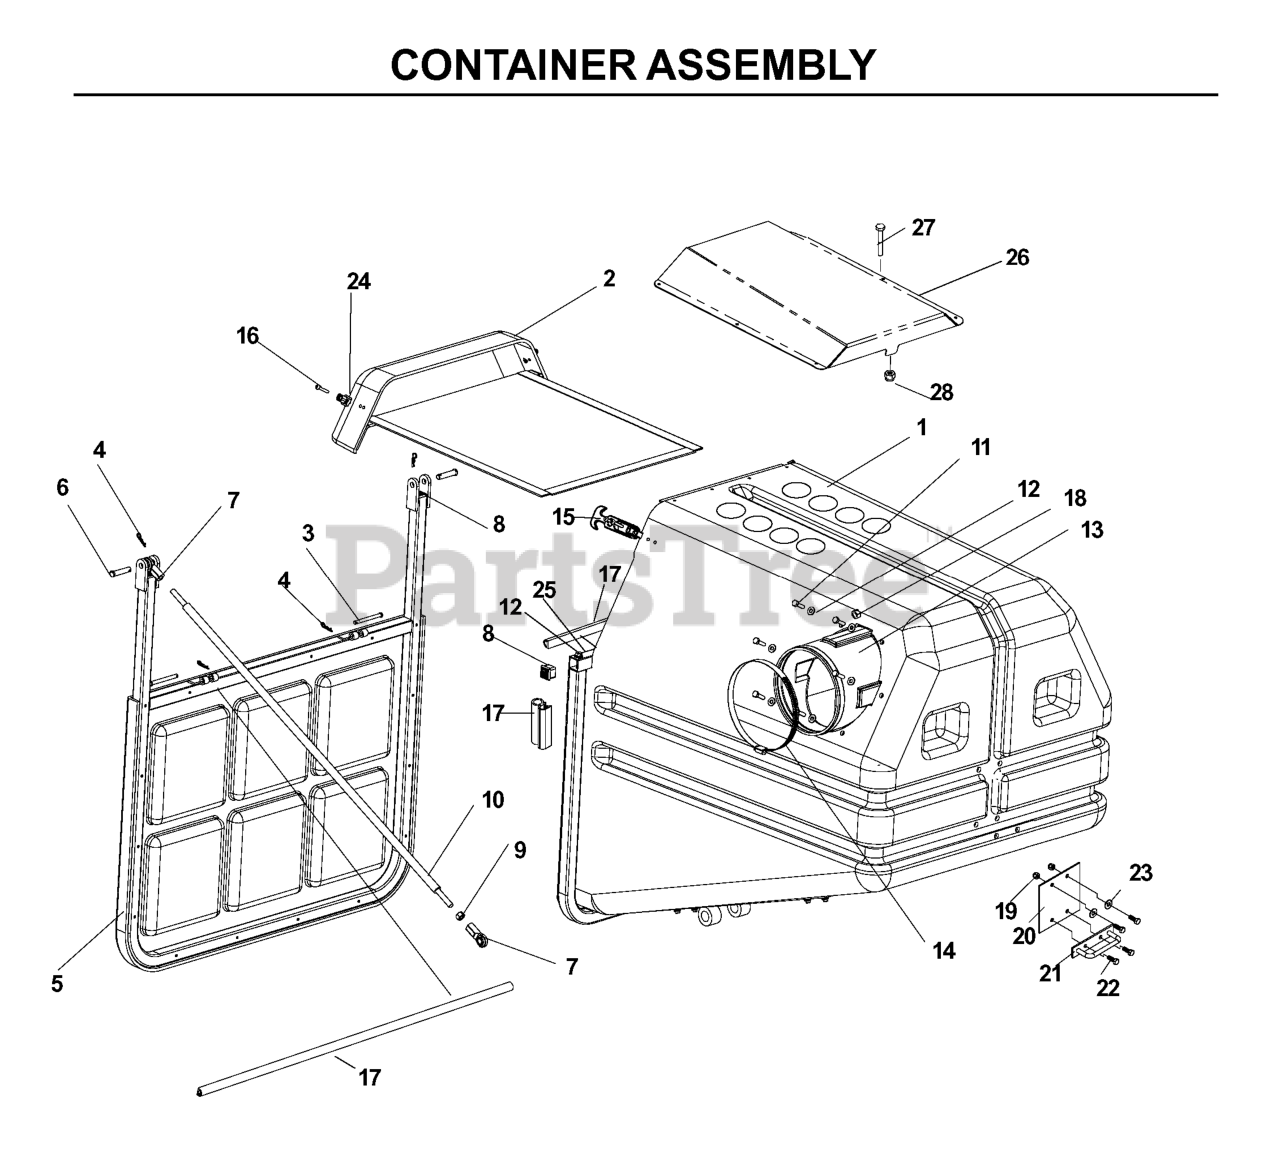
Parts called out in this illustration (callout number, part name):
1	CONTAINER ASM.
2	EXHAUST ASM.
3	CLEVIS PIN
4	PIN, HAIR COTTER #13 5/64 X 1
6	PIN
7	ROD END
8	FINISHING PLUG
9	HEX NUT 3/8-24
10	PAINTED ARM BLACK
11	BOLT, 1/4-28 X 1
12	WASHER, 1/4
14	HOSE CLAMP
16	PANHEAD SCREW
17	SVC KIT, DOOR SEAL
18	Nut, Hex, Nylon Lock, 1/4"-20
19	NUT 3/8 NYLOC
20	BACK PLATE
21	CONTAINER LATCH WELDMENT BLACK
22	BOLT, 3/8-16 X 1
23	WASHER, 3/8
24	LATCH BASE
25	BOLT 1/4-20 X 2"
27	SCR #10-24 X 3/4
28	NUT 10-24 NYLOC
540000403	FLAT WASHER #10
540002004	Nut, Hex, Nylon Lock, #10-24
